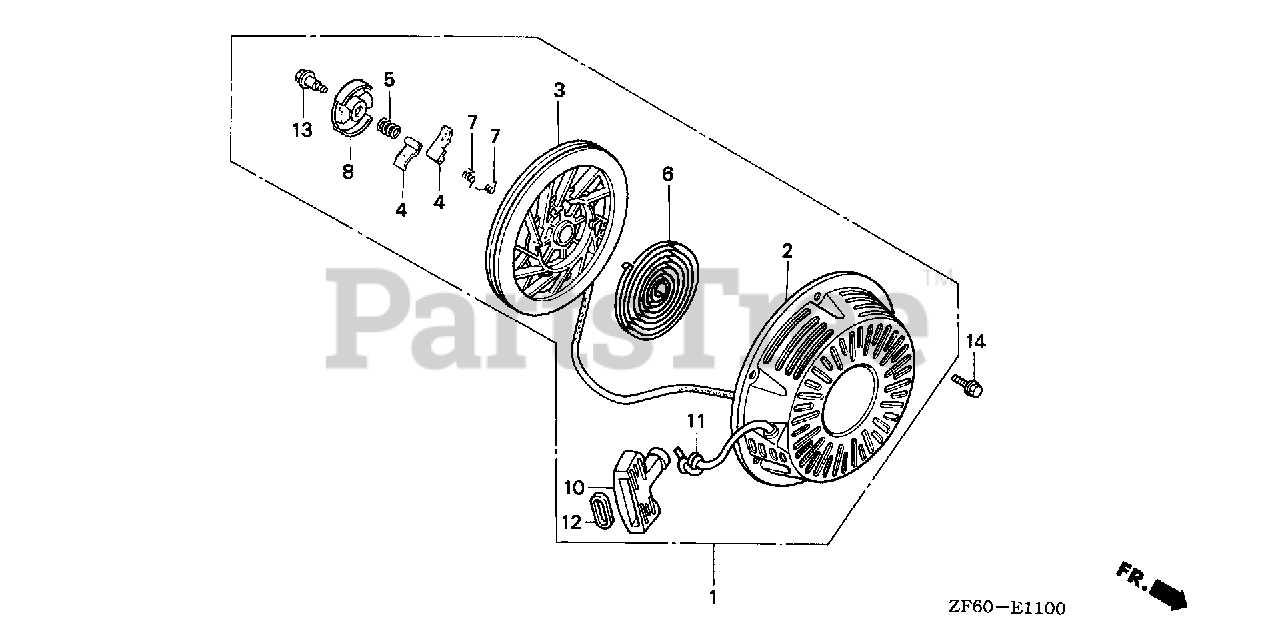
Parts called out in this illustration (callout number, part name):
1	STARTER ASSY., RECOIL *R280* (POWER RED)
2	CASE, RECOIL STARTER *R280* (POWER RED)
3	PULLEY, RECOIL STARTER
4	RATCHET, STARTER
5	SPRING, FRICTION
6	SPRING, STARTER RETURN
7	SPRING, RATCHET
8	RETAINER, SPRING
10	GRIP, STARTER
11	ROPE, RECOIL STARTER
12	REINFORCEMENT, GRIP
13	SCREW, CENTER
14	BOLT, FLANGE (6X8)
